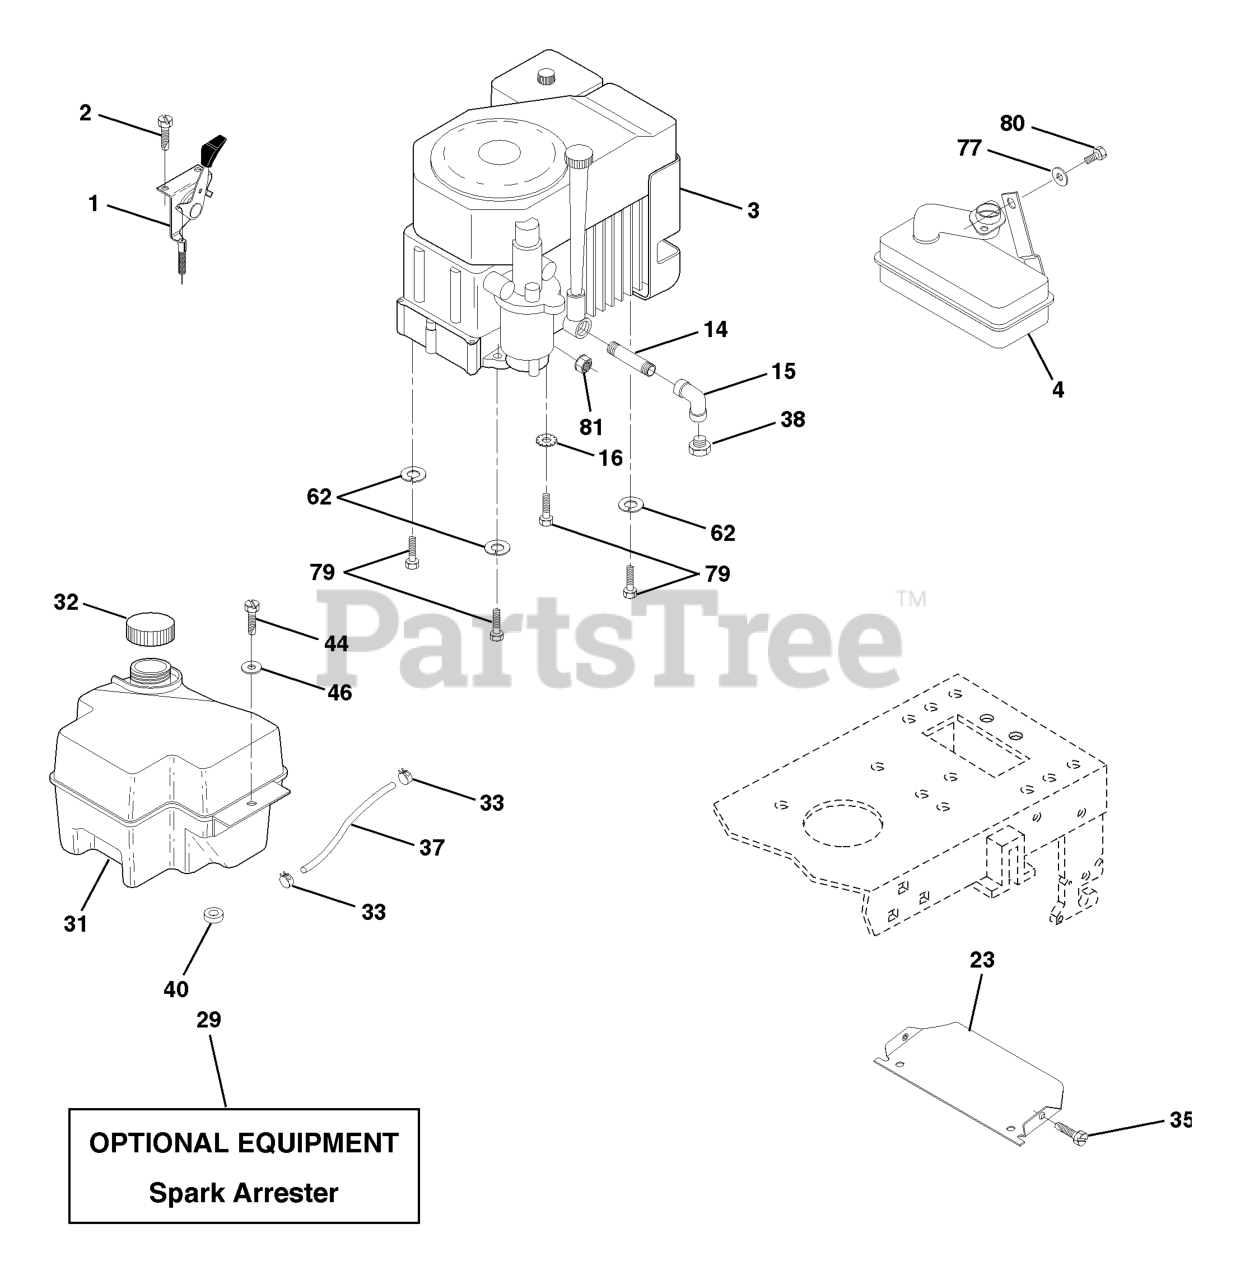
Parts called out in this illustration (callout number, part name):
1	CONTROL SWITCH 27 LH
2	SCREW LT
3	Engine Kohler, Model No. CV15S 15 HP
4	MUFFLER LT 12.5
14	Nipple Pipe 3/8 Npt X 3-1/2
15	ELBOW
16	WASHER EXT TOOTH LOCK 5/16
23	SHIELD HEAT
29	KIT.SPARK ARRESTOR 794945 B&S
31	FUEL TANK
32	FUEL CAP
33	HOSE CLAMP
35	SCREW.THDROL.5/16-18X3/4.TTY
37	LINE.FUEL.20
38	Plug Oil Drain
40	BUSHING.SNAP.NYL.BLK.
44	SCREW HEX CRT
46	WASHER
62	WASHER.LOCK.HVY.HLCL.SPR.5/16
77	WASHER
79	BOLT, HEX
80	Bolt Hex Hd 5/16-18 UNC x 1/2
81	NUT FLANGE 1/4-20 STARTER NUT
